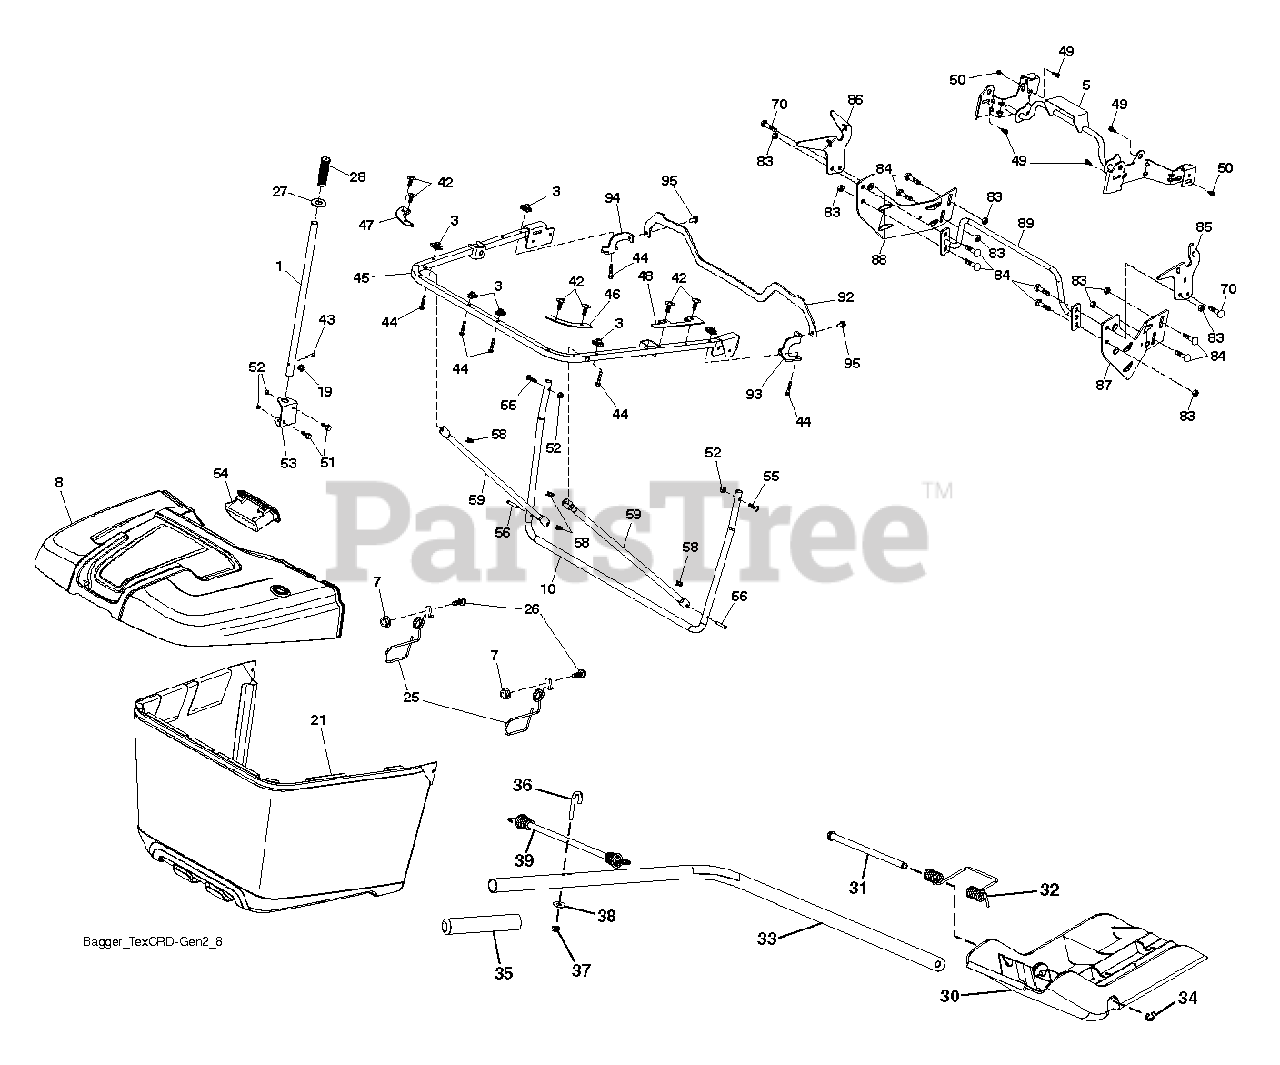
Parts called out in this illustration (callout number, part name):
1	TUBE.HANDLE.BAGGER.CRD/SRD.BLA
3	1/4-20 U NUT
5	FRAME TEX_CRD_GEN2 UPPER PIVOT
7	NUT T
8	COVER.BAG.NO_APP.CRD.GENII.498
10	FRAME TEX_CRD_GEN2 BAGGER FRAM
19	PIN.COTTER.5/16.BOW TI
21	BAG FRAME BAGGER ASSEMBLY. HUS
25	LATCH LATCH. BAG. CRD GEN 2
26	SCREW HEX CRT
27	GROMMET RUBBER GROMMET, DUMP T
28	GRIP.HANDLE.BLACK
30	PLUG PLUG
31	PIN PIN.HINGE
32	SPRING SPRING DOUBLE TORSION
33	SHAFT SHAFT TEX CRD MULCH PLU
34	E-RING.5/16"
35	GRIP GRIP MULCH PLUG HAND
36	BOLT BOLT J
39	BUBGEE BUBGEE TEX CRD
42	CLIP CHRISTMAS TREE CLIP
43	RIVET,DRILLED
45	FRAME TEX_CRD_GEN2 UPPER U FRA
46	CONNECTOR RIGHT BAGGER CORNER
47	CONNECTOR LEFT BAGGER CORNER C
48	BAFFLE BAGGER SIDE CLOSE-OUT
49	BOLT, SHOULDER 5/16-18
50	BOLT, 5/16-18 X 1 3/4
51	BOLT.CARR.SQNK.5/16-18UNC.X3/4
52	NUT.71038.31-18.HEX.NYLOCK
53	BRACKET DUMP HANDLE BRACKET, T
54	HANDLE BAGGER TOP FRONT HANDLE
55	BOLT
56	PIN.CLEVIS.183
58	RETAINER CLIP PM
59	TUBE BAGGER SPREADER TUBE, TEX
70	SCREW, 3/8-16X3/4
83	NUT
84	BOLT D
85	BRACKET.RH.PIVOT.MAN.DUMP.BLAC
86	BRACKET.LH.PIVOT.MAN.DUMP.BLAC
87	BRACKET.RH.MID.SUP.BAG.TEX.CRD
88	BRACKET.LH.MID.SUP.BAG.TEX.CRD
89	TUBE.WELD.OFSET.STRUT.BAG.X431
92	BRACKET.PNT.BAGGER.TOP.SUPPORT
93	BRACKET.PNT.RH.SUPPORT.ATTACH
94	BRACKET.PNT.LH.SUPPORT.ATTACH
95	SCREW
